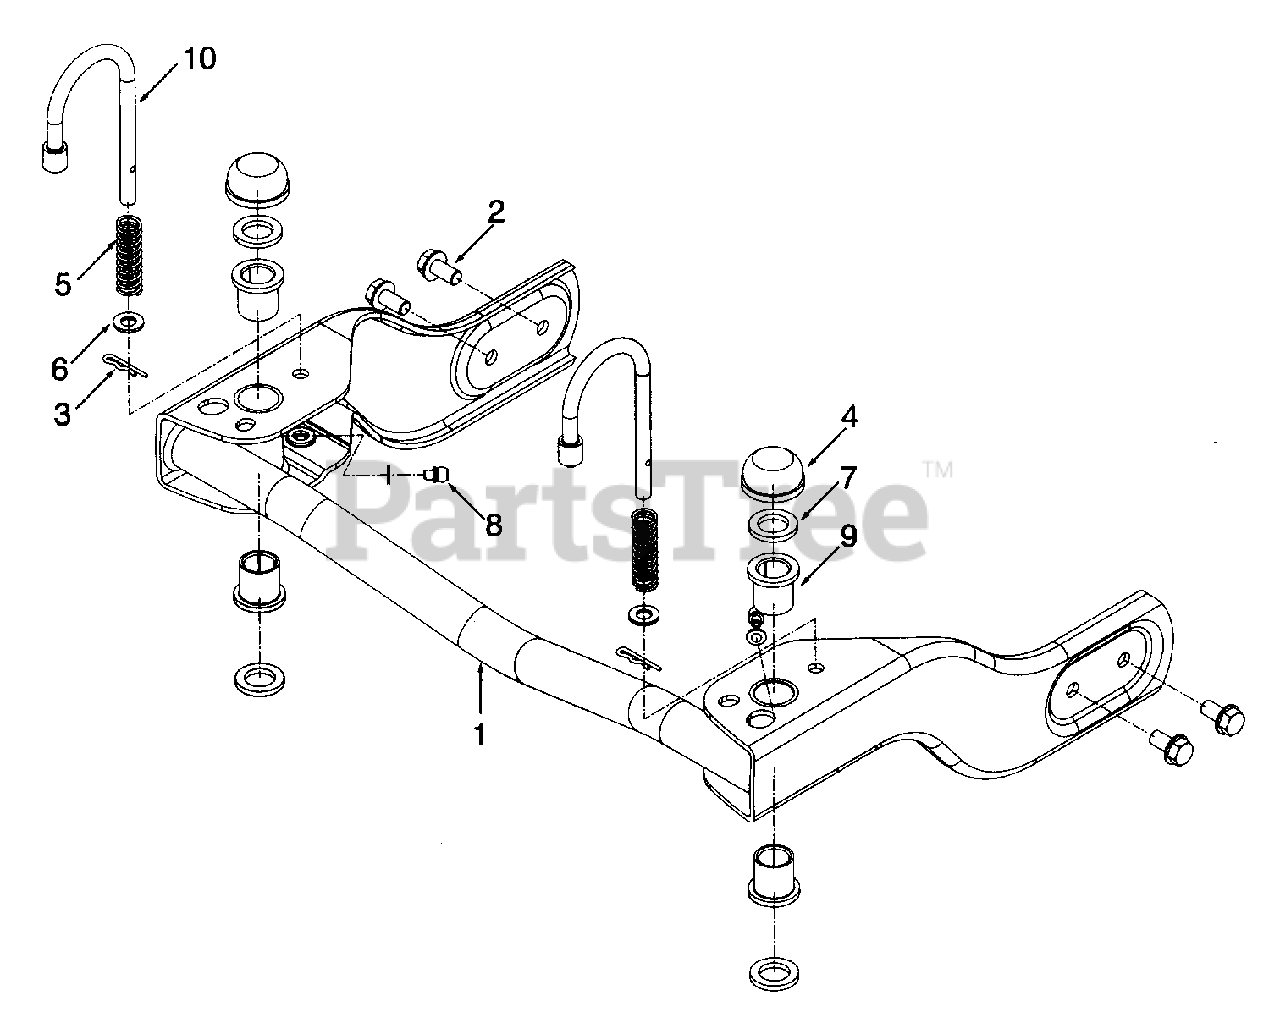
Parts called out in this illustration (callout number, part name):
2	Screw, Hex Wash. Hd. Tapp, 5/16-18 x .62
3	Pin, Internal Cotter
4	Cap, Push, 5/8
5	Spring, Compression
6	Washer, Flat, .330 x .630 x .06
7	Washer, Flat, .64 x 1.12 x .12
8	Fitting, Lube, 3/16
9	Bearing, Flange, .632 ID
10	Pin, Front Wheel Lock
